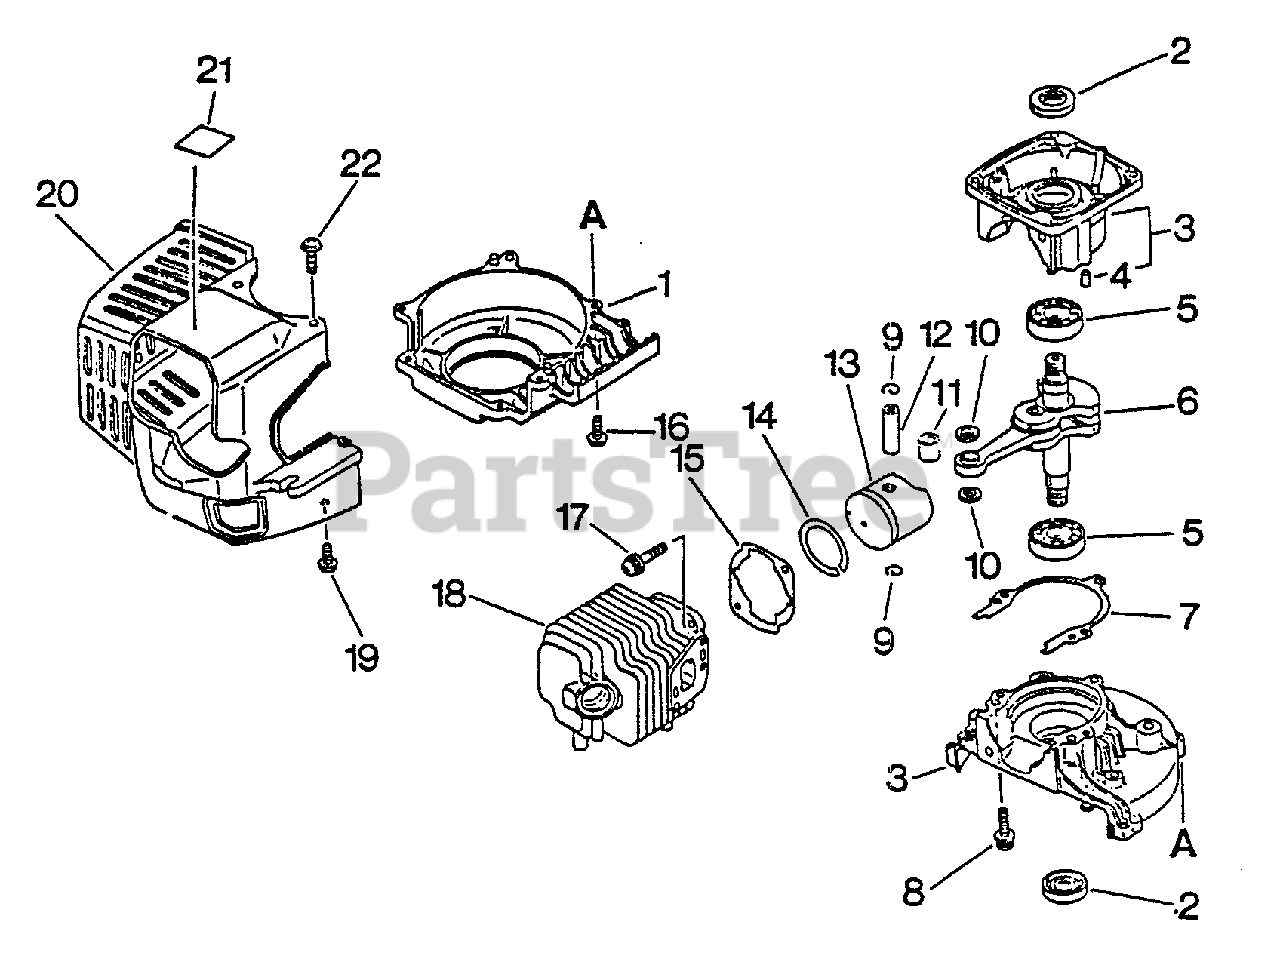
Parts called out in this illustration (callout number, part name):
1	COVER, FAN
2	SEAL, OIL 12
3	CRANKCASE KIT
4	PIN, LOCATING 4
5	BEARING, BALL - 6201 C3
6	CRANKSHAFT ASSY
7	GASKET, CRANKCASE
8	SCREW 5×28
9	RING, SNAP
10	WASHER, THRUST
11	BEARING, NEEDLE
12	PIN, PISTON 8
13	PISTON
14	RING, PISTON
15	GASKET, CYLINDER
16	SCREW 4×14
17	BOLT 5×22
19	SCREW 4×16
20	COVER, ENGINE - GRAY
21	LABEL, MODEL
22	SCREW 4×12
